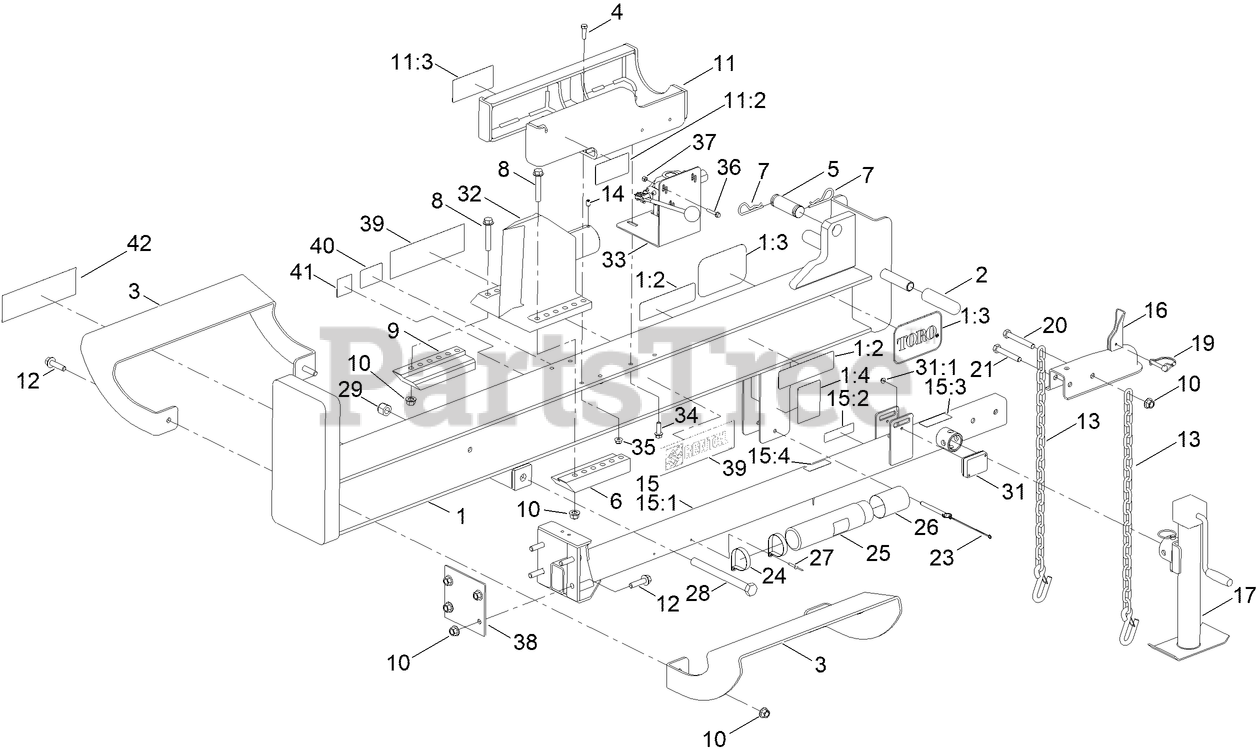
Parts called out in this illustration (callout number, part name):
1	BEAM ASM
1:3	DECAL
1:4	DECAL-WARNING, PIN
2	GRIP-HANDLE
3	PLATE-CATCH
4	SCREW-HH
5	PIN-PIVOT
6	BAR-SLIDE, LH
7	PIN-HAIR
8	SCREW-HF
9	BAR-SLIDE, RH
10	NUT-LOCK
11	DISLODGE BRACKET W/DECALS
11:2	DECAL-WARNING, PINCH POINT
11:3	DECAL-CAUTION, DANGEROUS AREA
12	SCREW-HF
13	CHAIN-SAFETY, TRAILER
14	SCREW-SET
15	DECAL ASM-TUBE
15:1	TONGUE ASM [RED]
15:2	DECAL-ARRESTOR, SPARK
15:3	DECAL-CAUTION
15:4	DECAL-WARNING, PINCH POINT
16	RECEIVER-BALL HITCH
19	PIN-LOCK
20	SCREW-HH
21	SCREW-HH
24	CLAMP-R
25	TUBE-MANUAL
26	CAP-HOUSING
27	RIVET-BLIND
28	BOLT-HH
29	NUT-LOCK, NI
31	LAMP-MARKER, FRONT SIDE
31:1	NUT-KEPS
32	WEDGE [BLACK]
33	BRACKET-VALVE
34	SCREW-HHF
35	NUT-HF, NI
36	SCREW-HHF
37	NUT-LOCK, NI
38	PLATE - BACKING
39	DECAL-RHHLG3X10
40	DECAL-CPER0011
41	DECAL-CPER0003
42	DECAL-CPER0002
